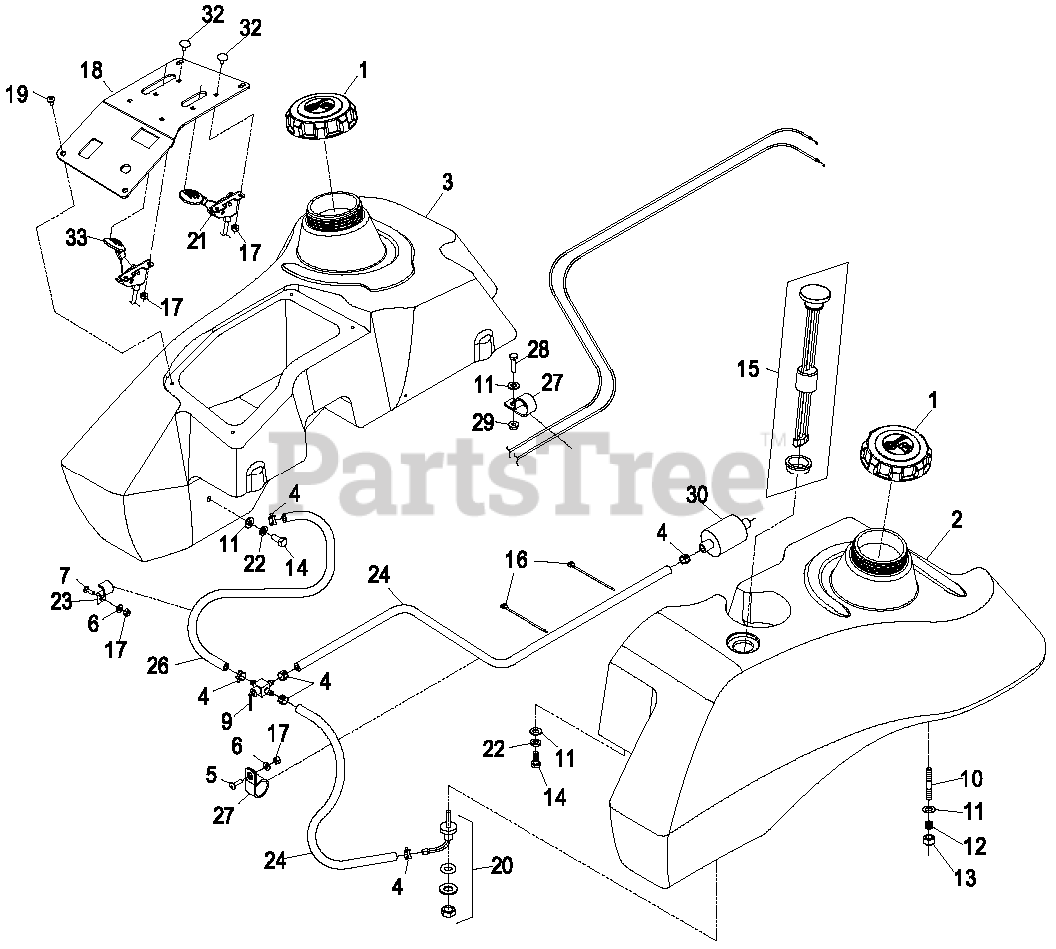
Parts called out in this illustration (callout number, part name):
1	CAP-FUEL, GAS
2	KIT,FUEL TANK LH LZXS
3	KIT,FUEL TANK RH LZXS
5	SCREW-HEAD, TRUSS
6	WASHER-FLAT
7	BOLT-CARR
9	VALVE-FUEL
10	STUD
11	WASHER-PLAIN
12	SPRING-TANK, FUEL
13	NUT-LOCK, NI
14	SCREW-HH
15	KIT, CT FUEL GAGE REPL.
16	TIE-PLASTIC
17	NUT-LOCK, NI
18	PANEL,CONTROL W/DECALS
19	SCREW-PPH
20	FITTING-FUEL, BULKHEAD
21	CONTROL-THROTTLE
22	WASHER-LOCK
23	CLIP-HALF, LOOM
24	HOSE-FUEL
26	HOSE-FUEL
27	CLIP-LOOM
28	SCREW-HH
32	BOLT-CARR
33	CONTROL,CHOKE
